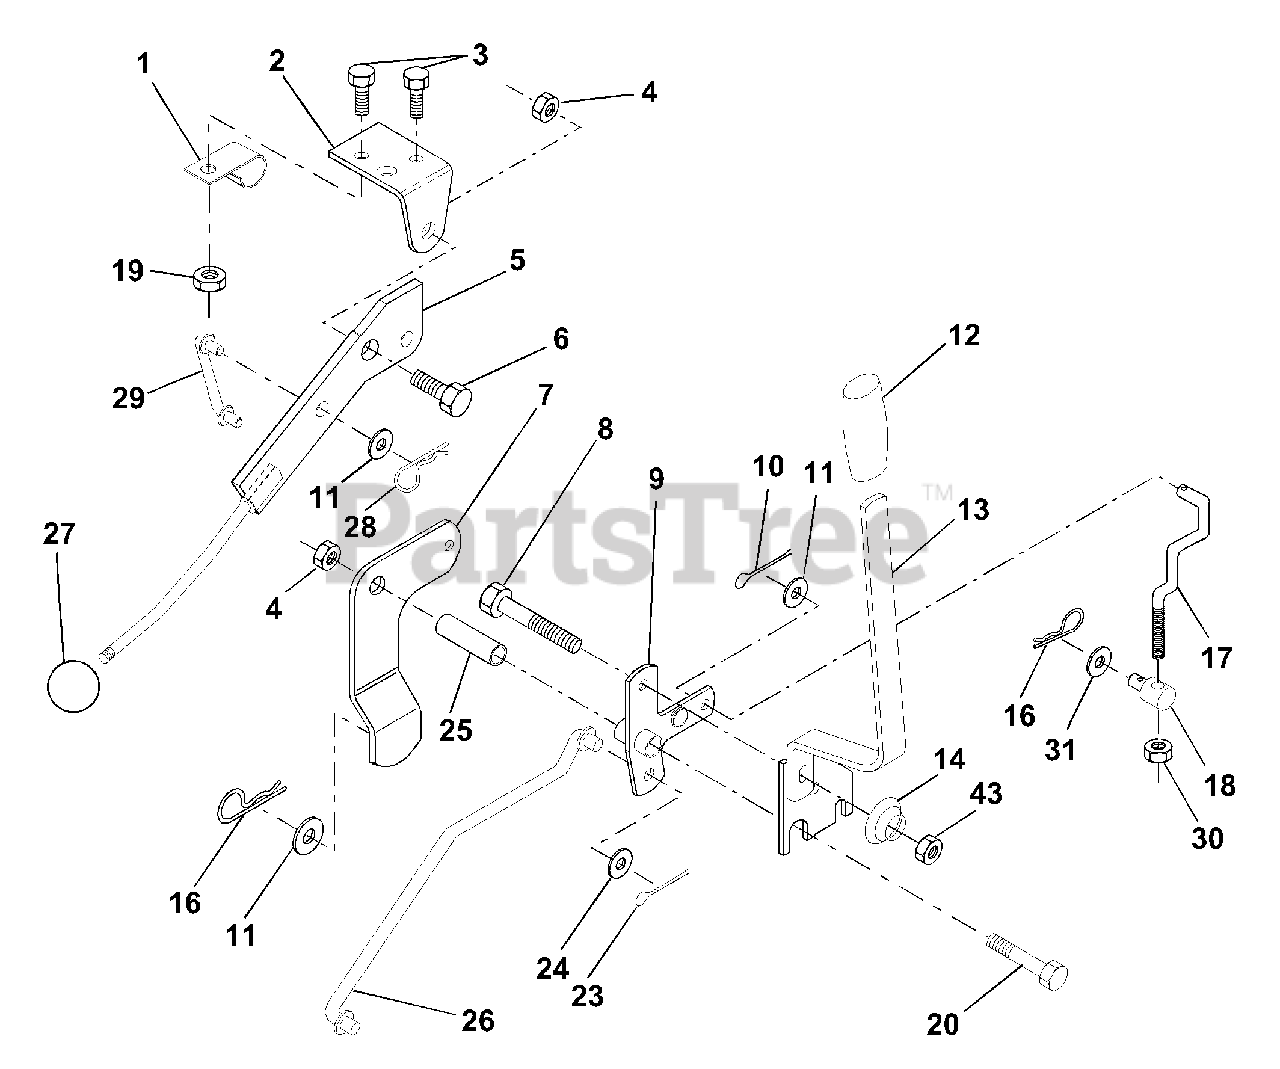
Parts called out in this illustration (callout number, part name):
1	Clip, Insulated
2	Bracket, Mower Clutch
3	Bolt, Fin. Hex 1/4-20 UNC x 1/2 Gr. 5
4	Nut, Crownlock 3/8-16 UNC
5	Assembly, Clutch Lever
6	Bolt, Shoulder
7	Assembly, Mower Clutch Arm
8	Bolt, Hex 3/8-16 UNC x 2-1/4
9	Assembly, Bellcrank Lift
10	Pin, Cotter 1/8 x 3/4
11	Washer 13/32 x 13/16 x 16 Ga.
12	Grip, Handle
13	Assembly, Lift Handle
14	Spring, Compression
16	Retainer, Spring
17	Link, Front Lift
18	Trunnion, Threaded 3/8-16
19	Nut, Crownlock 1/4-20
20	Bolt, Fin. Hex 3/8-16 UNC x 2-3/4
23	Pin, Cotter 1/8 x 1
24	Washer 17/32 x 1 x 12 Ga.
25	Tube, Spacer
26	Rod, Mower Lift
28	Retainer Spring
29	Link, Mower Clutch
30	Nut Hex Jam 3/8-16 x 1.30
31	Washer 13/32 x 1-1/4 x 12 Ga.
43	Nut Lock Flg 3/8-16
